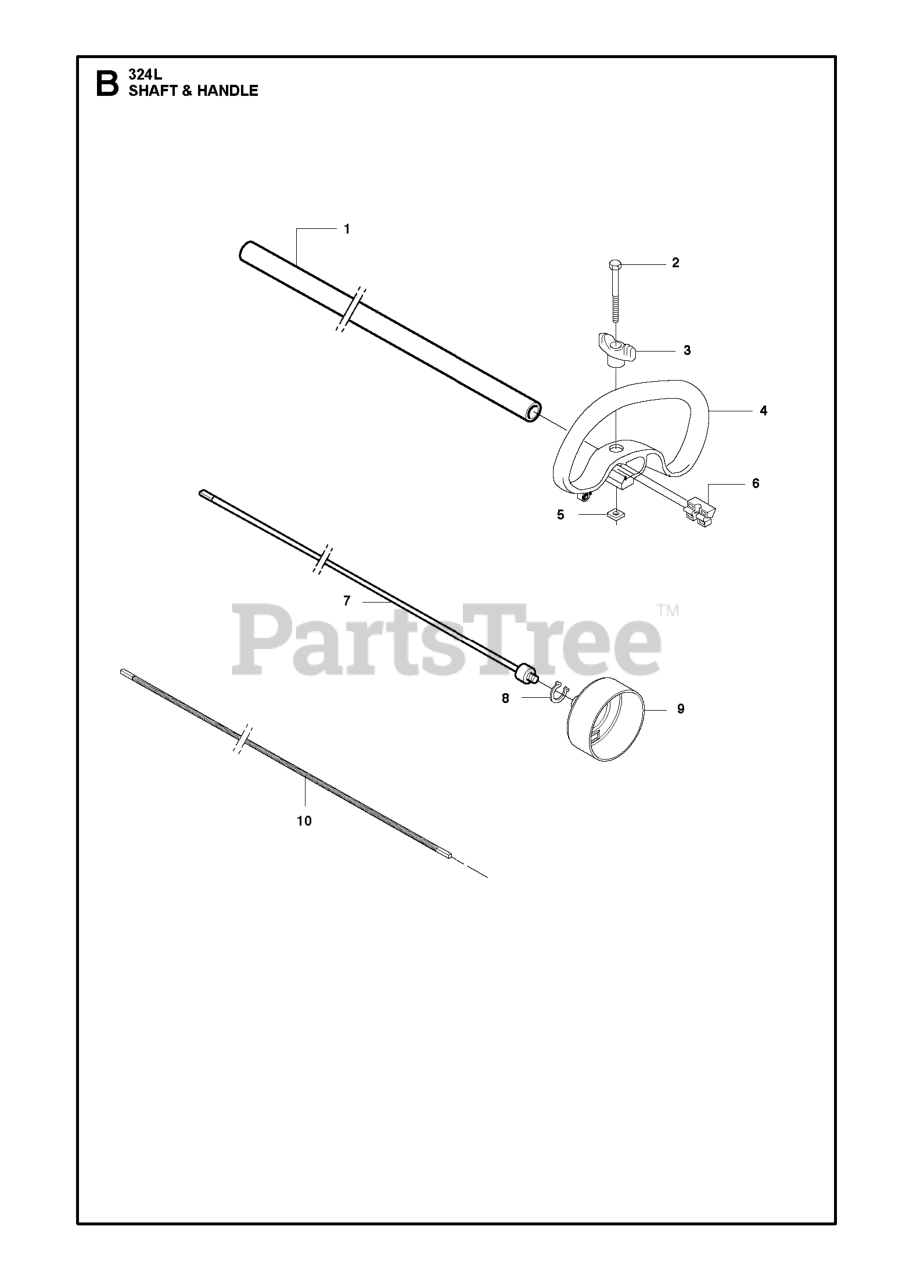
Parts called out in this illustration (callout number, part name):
1	SHAFT CPL
2	SCREW M6X50
4	HANDLE, LOOP
6	SPACER PLASTIC
7	DRIVE SHAFT
8	RETAINING RING SGA 10
9	CLUTCH DRUM ASSY
10	DRIVE SHAFT FLEX
